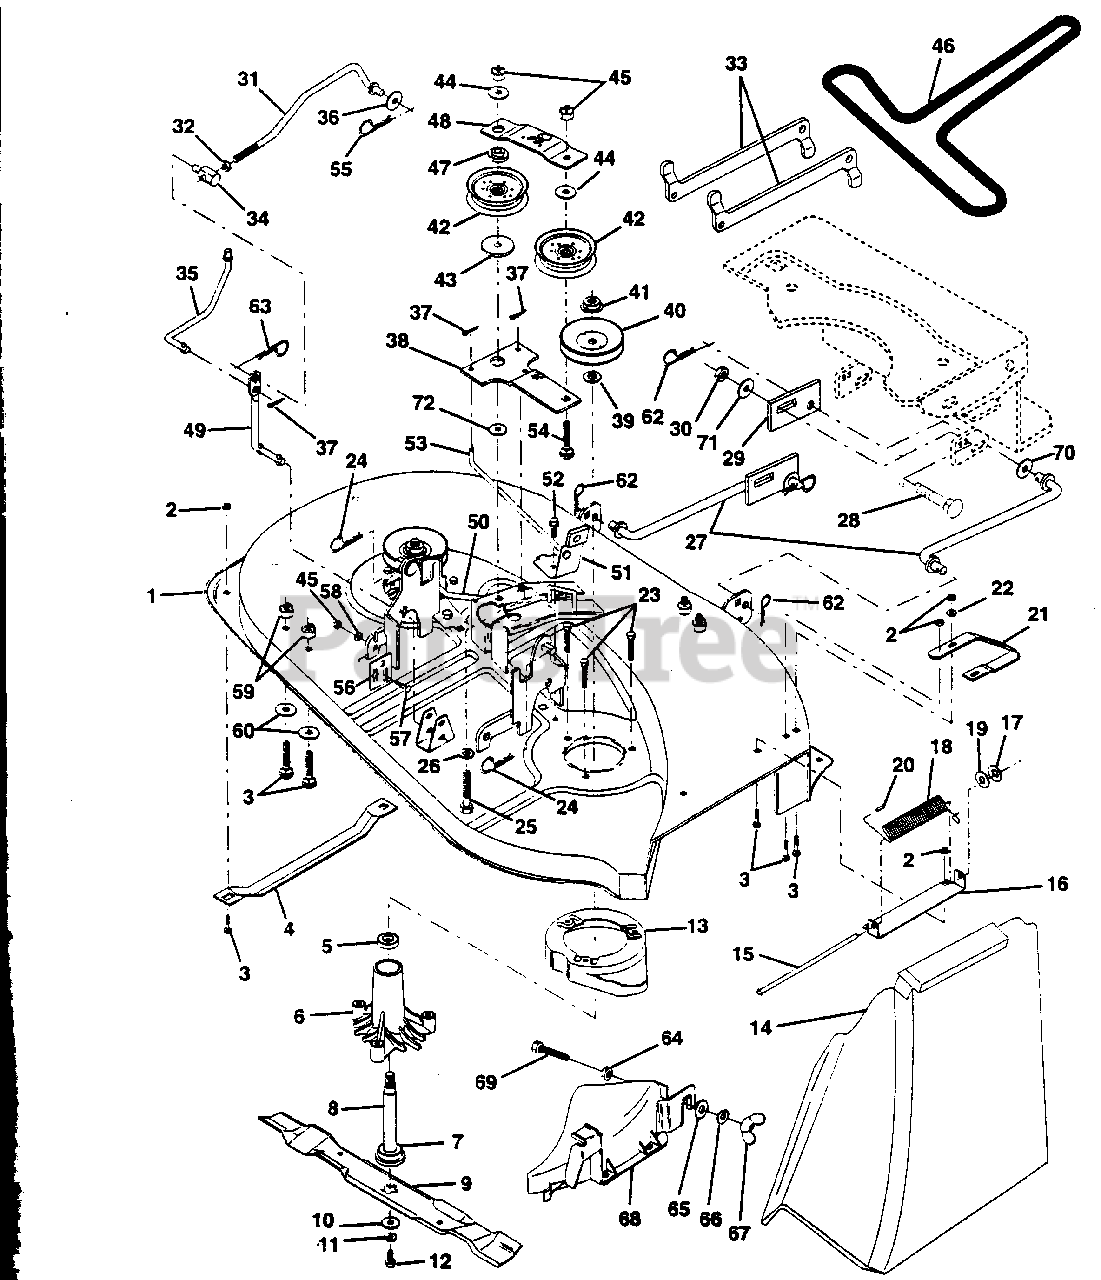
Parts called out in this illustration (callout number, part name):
1	Mower Deck Assembly (AYP part number)
2	Nut,Lock Hex w/Ins 5/16-18 (AYP part number)
3	Bolt, Carriage 5/16-18 x 3/4
4	Runner, L.H. (AYP part number)
5	Bearing (AYP part number)
6	Housing, Mandrel
7	Bearing (AYP part number)
8	Shaft and Bearing Assembly, Mandrel (Inc. 7)
10	Washer, Hardened (AYP part number)
11	Washer, Lock 3/8 (AYP part number)
12	Bolt, Hex 3/8-24 x 1-1/4 Grade 8 (AYP part number)
13	Stripper, Round (AYP part number)
14	Shield, Deflector (AYP part number)
15	Rod, Hinge (AYP part number)
16	Bracket Assembly, Deflector (AYP part number)
17	Pushnut (AYP part number)
18	Spring, Deflector (AYP part number)
19	Washer 11/32 x 5/8 x 16 Gauge (AYP part number)
20	Cap, Sleeve (AYP part number)
21	Runner, R.H. (AYP part number)
22	Washer 11/32 x 3/4 x 16 Gauge (AYP part number)
23	Bolt 5/16-18 x 1.25 (AYP part number)
24	Retainer, Spring (AYP part number)
25	Bolt, Carriage 3/8-16 x 2-1/4 (AYP part number)
26	Washer 13/32 x 1 x 12 Gauge (AYP part number)
27	Link Assembly, Front (AYP part number)
28	Bolt, RdHd SqNk 3/8-16 x 1 (AYP part number)
29	Plate, Slide Link (AYP part number)
30	Nut, Lock Hex w/Wsh 3/8-16 (AYP part number)
31	Clutch Rod, Primary (AYP part number)
32	Nut, Hex, Jam 3/8-16 (AYP part number)
33	Arm, Suspension, Rear (AYP part number)
34	Trunnion 3/8-16 (AYP part number)
35	Clutch Rod, Secondary (AYP part number)
36	Washer 13/32 x 13/16 x 16 Gauge (AYP part number)
37	Pin, Cotter 3/32 x 3/4 (AYP part number)
38	Idler Arm (AYP part number)
39	Washer .150 Thick (AYP part number)
40	Pulley, Mandrel (AYP part number)
41	Nut, Flangelock 9/16
42	Pulley, Flat Idler (AYP part number)
43	Spacer, Retainer (AYP part number)
44	Washer 13/32 x 1 x 12 Gauge (AYP part number)
45	Nut,Lock Hex w/Wsh 3/8-16 (AYP part number)
46	Belt
47	Spacer, Idler Arm (AYP part number)
48	Stiffener, Idler Arm (AYP part number)
49	Rod, Pivot (AYP part number)
50	Rod, Brake, L.H. (AYP part number)
51	Brake Assembly (AYP part number)
52	Screw, Hex Washer Head, Thd., Roll. 5/16-18 x 3/4
53	Rod, Brake, R.H. (AYP part number)
54	Bolt, Carriage 3/8-16 x 1-3/4 Grade 5 (AYP part number)
55	Spring, Retainer (AYP part number)
56	Adjustment Plate, Rear Link, L.H. (AYP part number)
57	Bolt, Carriage 3/8-16 x 1 (AYP part number)
58	Washer 13/32 x 3/4 x 12 Gauge (AYP part number)
59	Locknut, Hex, with Washer Insert 5/16-18 (AYP part number)
60	Washer 11/32 x 11/16 x 12 Gauge (AYP part number)
62	Retainer, Spring (AYP part number)
63	Retainer, Spring (AYP part number)
64	Nut, Centerlock 3/8-16 (AYP part number)
65	Washer 13/32 x 1-1/4 x 16 Gauge (AYP part number)
66	Washer, Lock 3/8 (AYP part number)
67	Nut, Wing (AYP part number)
68	Cover, Asm Mulching (AYP part number)
69	Bolt, 3/8-16 x 1-1/4 (AYP part number)
70	Washer 1/2 x 1-1/4 x 16 Gauge (AYP part number)
71	Washer, Flat 13/32 x 1 x 10 Gauge (AYP part number)
72	Washer, Hardened (AYP part number)
